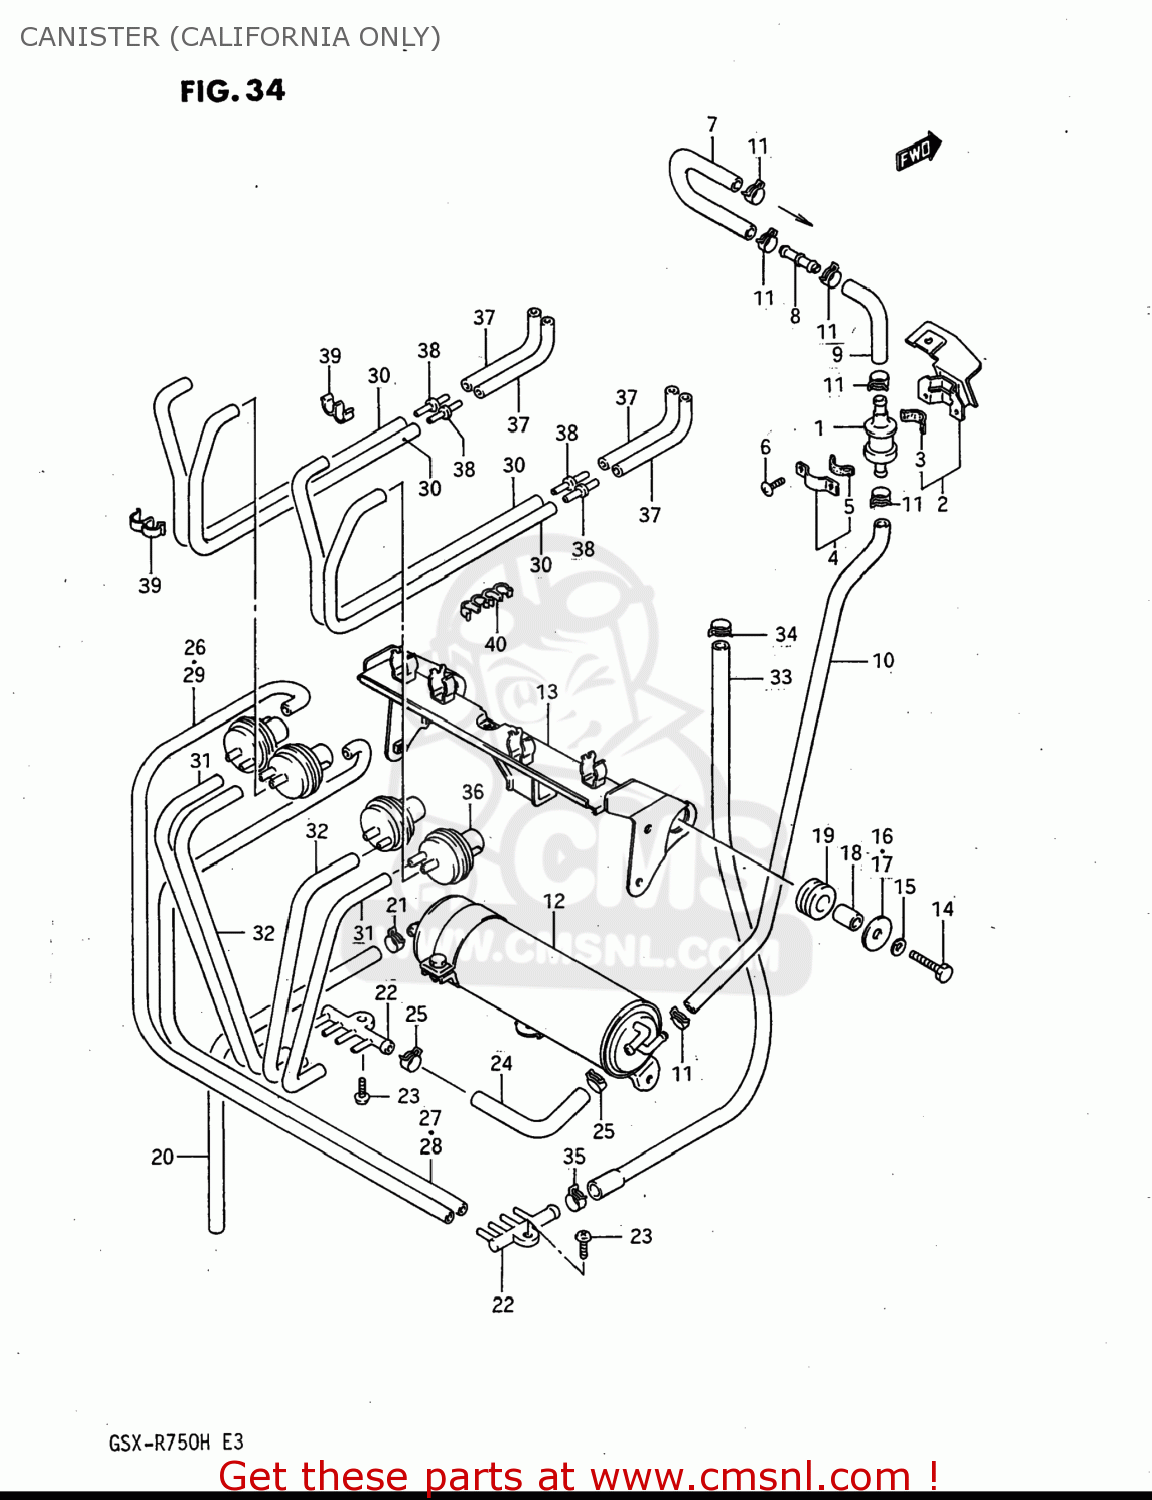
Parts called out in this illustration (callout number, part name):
1	VALVE,FUEL TANK BREATHER
2	(CA) PLATE,FRONT,TANK BRACKET
3	CUSHION
4	PLATE,FUEL TANK BREATHER NO.2
5	CUSHION
6	SCREW
7	HOSE
8	UNION
9	HOSE
10	HOSE
11	(CA) CLIP
12	(CA) CANISTER ASSEMBLY,CHARCOAL
13	(CA) BRACKET COMP,CANISTER
14	BOLT
15	WASHER
16	WASHER
17	WASHER (6.5X22X1.6)
18	SPACER(6.5X11.5X12)
19	CUSHION
20	HOSE
21	CLAMP
22	SEPARATOR
23	SCREW
24	HOSE
25	CLAMP
26	HOSE
27	(CA) HOSE
28	HOSE
29	HOSE
30	HOSE
31	HOSE
32	HOSE
33	HOSE
34	(CA) CLIP
35	CLAMP
36	(CA) VALVE,VACUUM CONT
37	HOSE
38	2 WAY
39	CLAMP
40	CLIP
